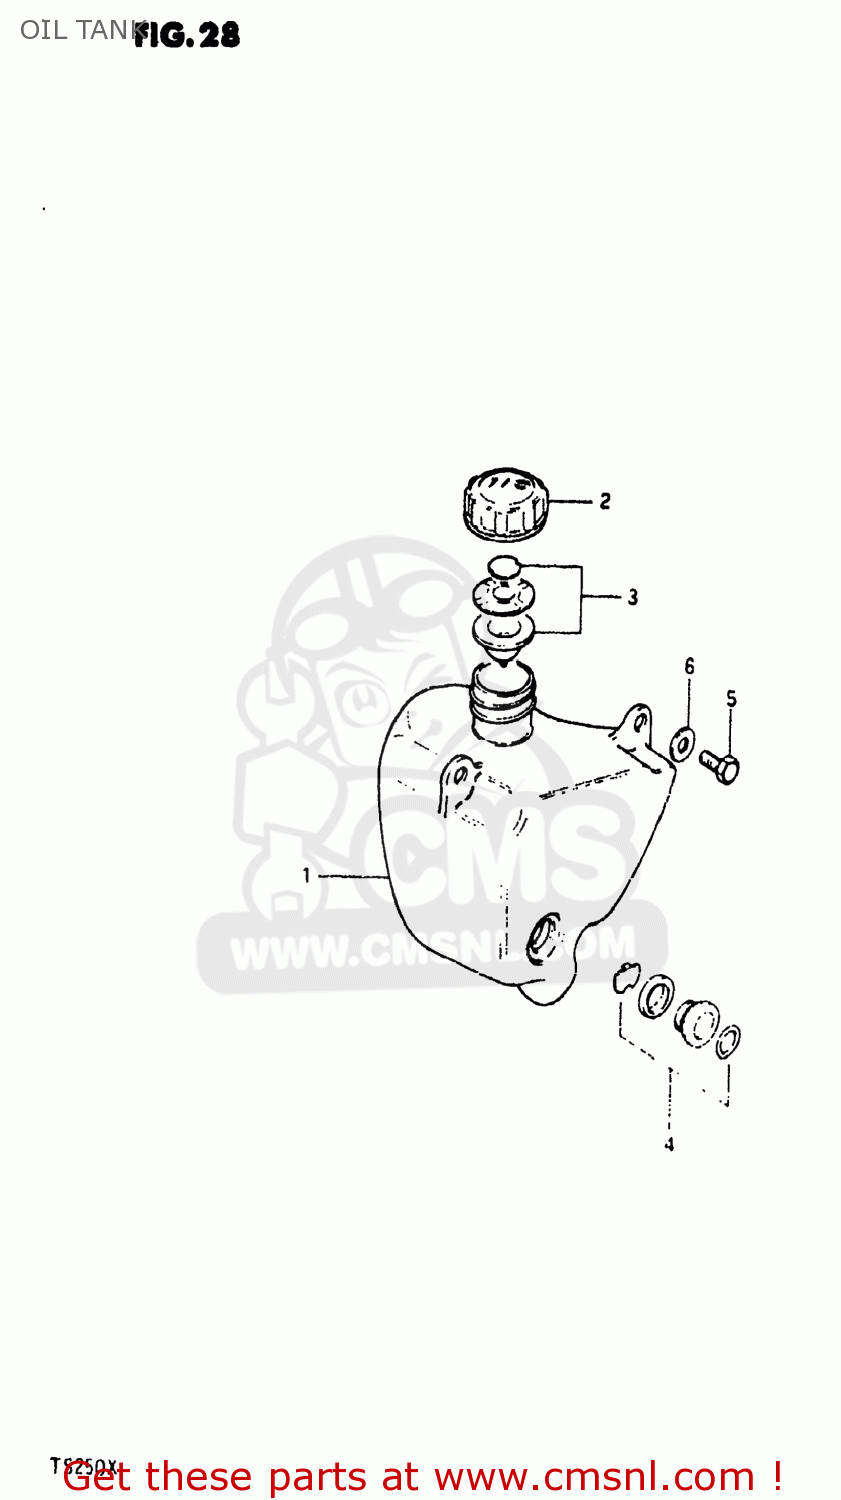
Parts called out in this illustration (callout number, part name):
1	TANK,OIL
2	CAP,OIL TANK
3	GASKET SET (NAS)
4	LENS SET,OIL LEVEL
5	BOLT, UPPER
6	WASHER
